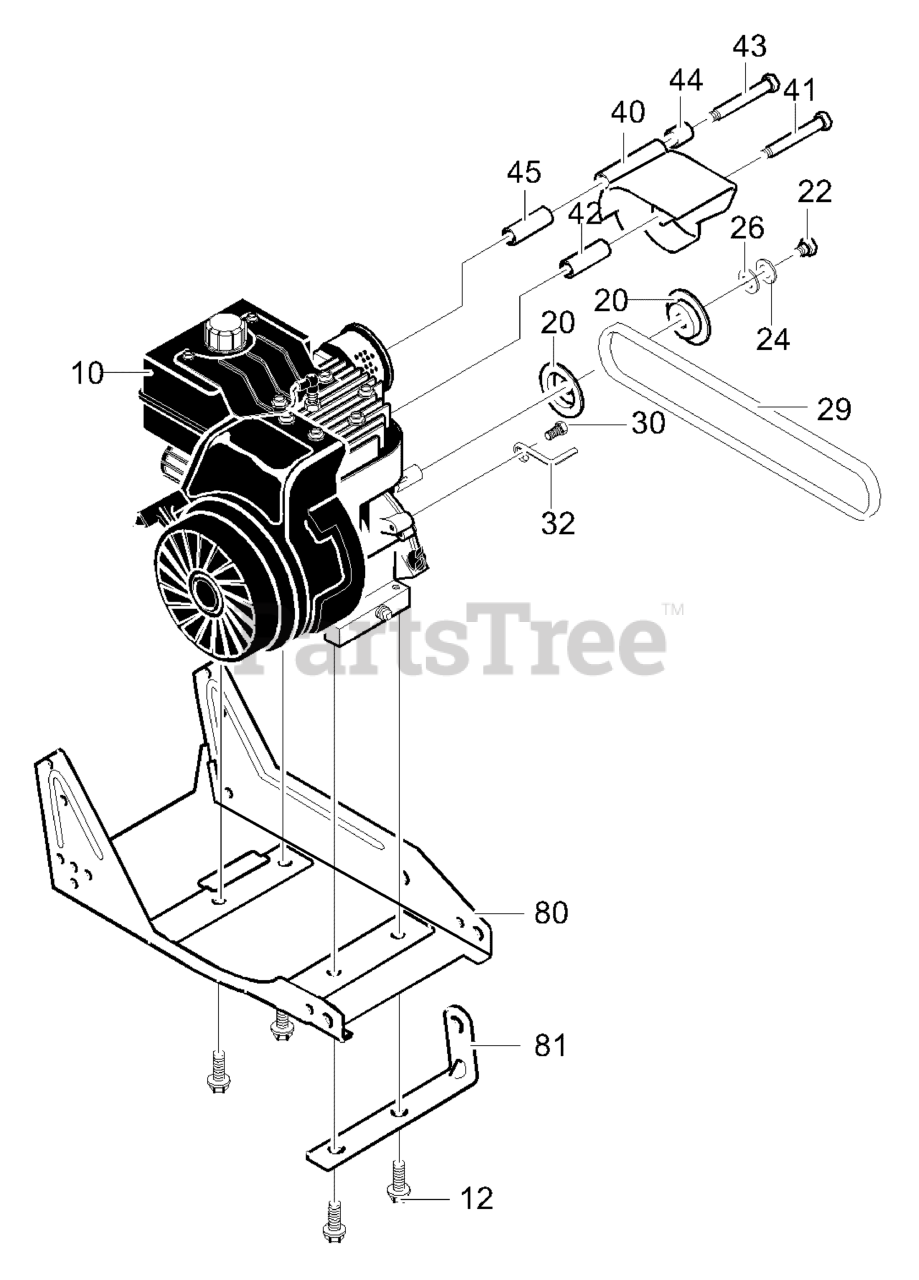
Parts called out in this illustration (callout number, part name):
10	Engine
12	Screw, 3/8-16 x 1.00
20	Pulley, Half
22	Screw, 5/16-24 x 1.00
26	Flatwasher
29	Belt, V4L 32.60LG
30	Screw and Washer Assy
32	Guide, Belt
40	Cover, Engine Pulley
41	Screw, 5/16-24 x 3.00
42	Spacer, Sleeve
43	Screw, 5/16-24 x 3.75
45	Spacer, Sleeve
80	Frame, Assy. Edger
